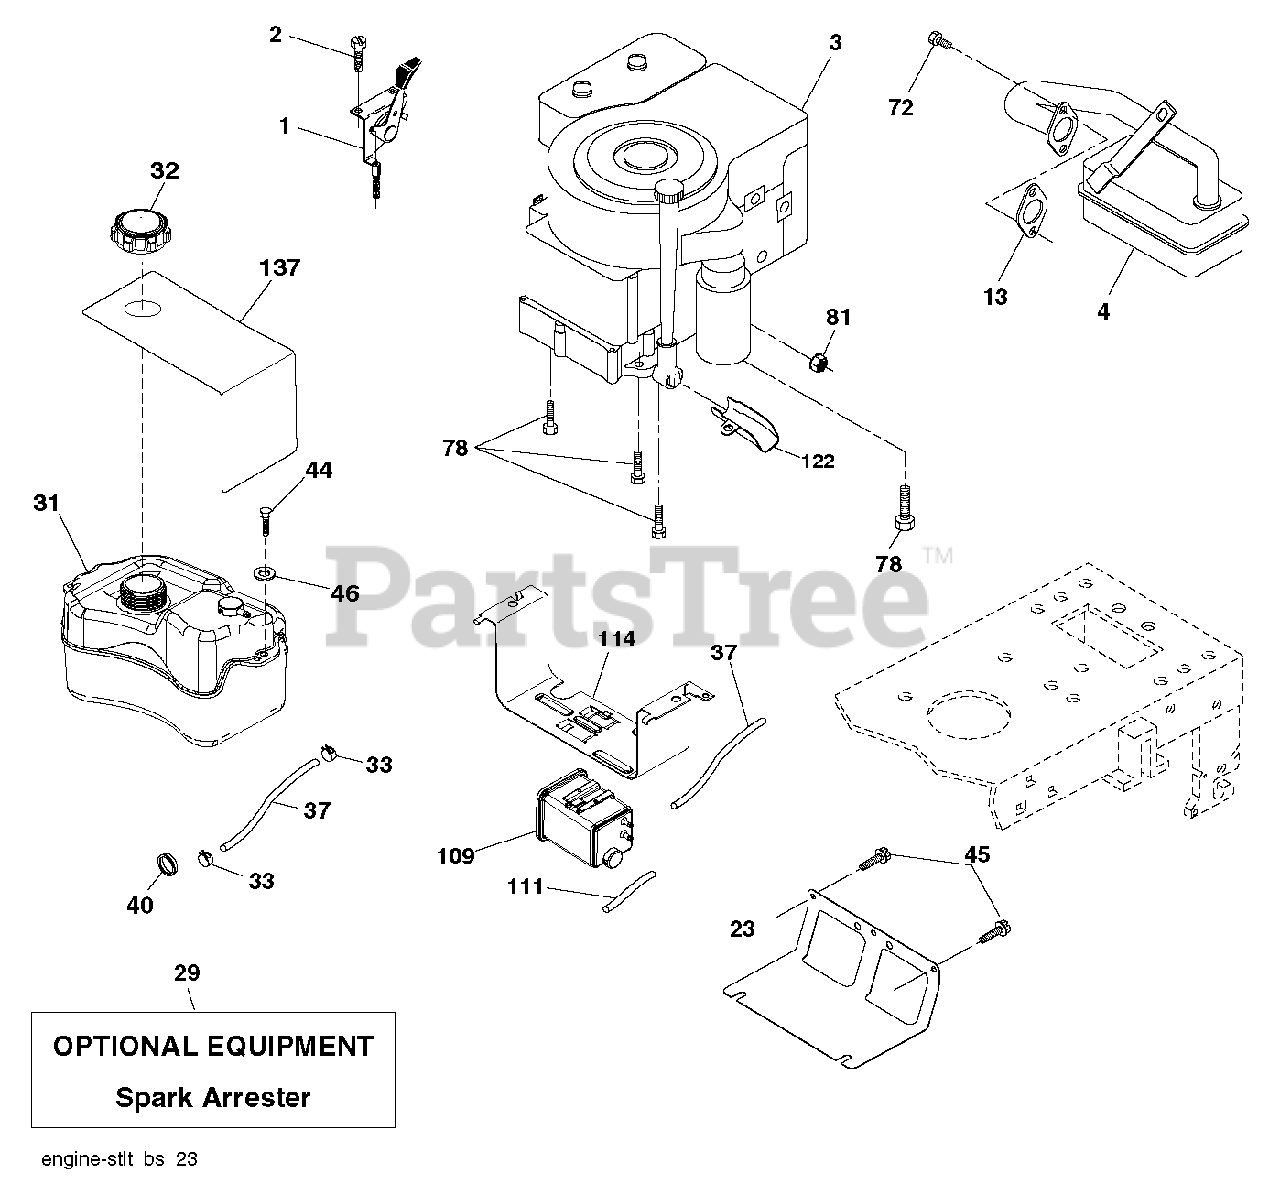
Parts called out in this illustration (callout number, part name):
1	CONTROL.THROTTLE/CHOKE.BLACK
4	MUFFLER.LT.BRIGGS.14HP.IC/OHV
23	SHIELD.BROWNING.DBR.GUARD
29	KIT.SPARK ARRESTOR(392390 B&S)
31	TANK ASM.FRONT.CARB
32	CAP ASM.FUEL.2.25"FRT.CARB
33	HOSE CLAMP
37	LINE.FUEL.20"FRONT.EMI
40	GROMMET T
44	SCREW HEXWSHR 1/4-20X3/4
45	SCREW, 3/8-16X3/4
46	WASHER
72	SCREW.SOCKET HD.5/16-1
78	SCREW.3/8-16
81	NUT
109	CANNISTER, CARBON
111	RP PURGE LINE
122	EXTENSION DRAIN OIL
